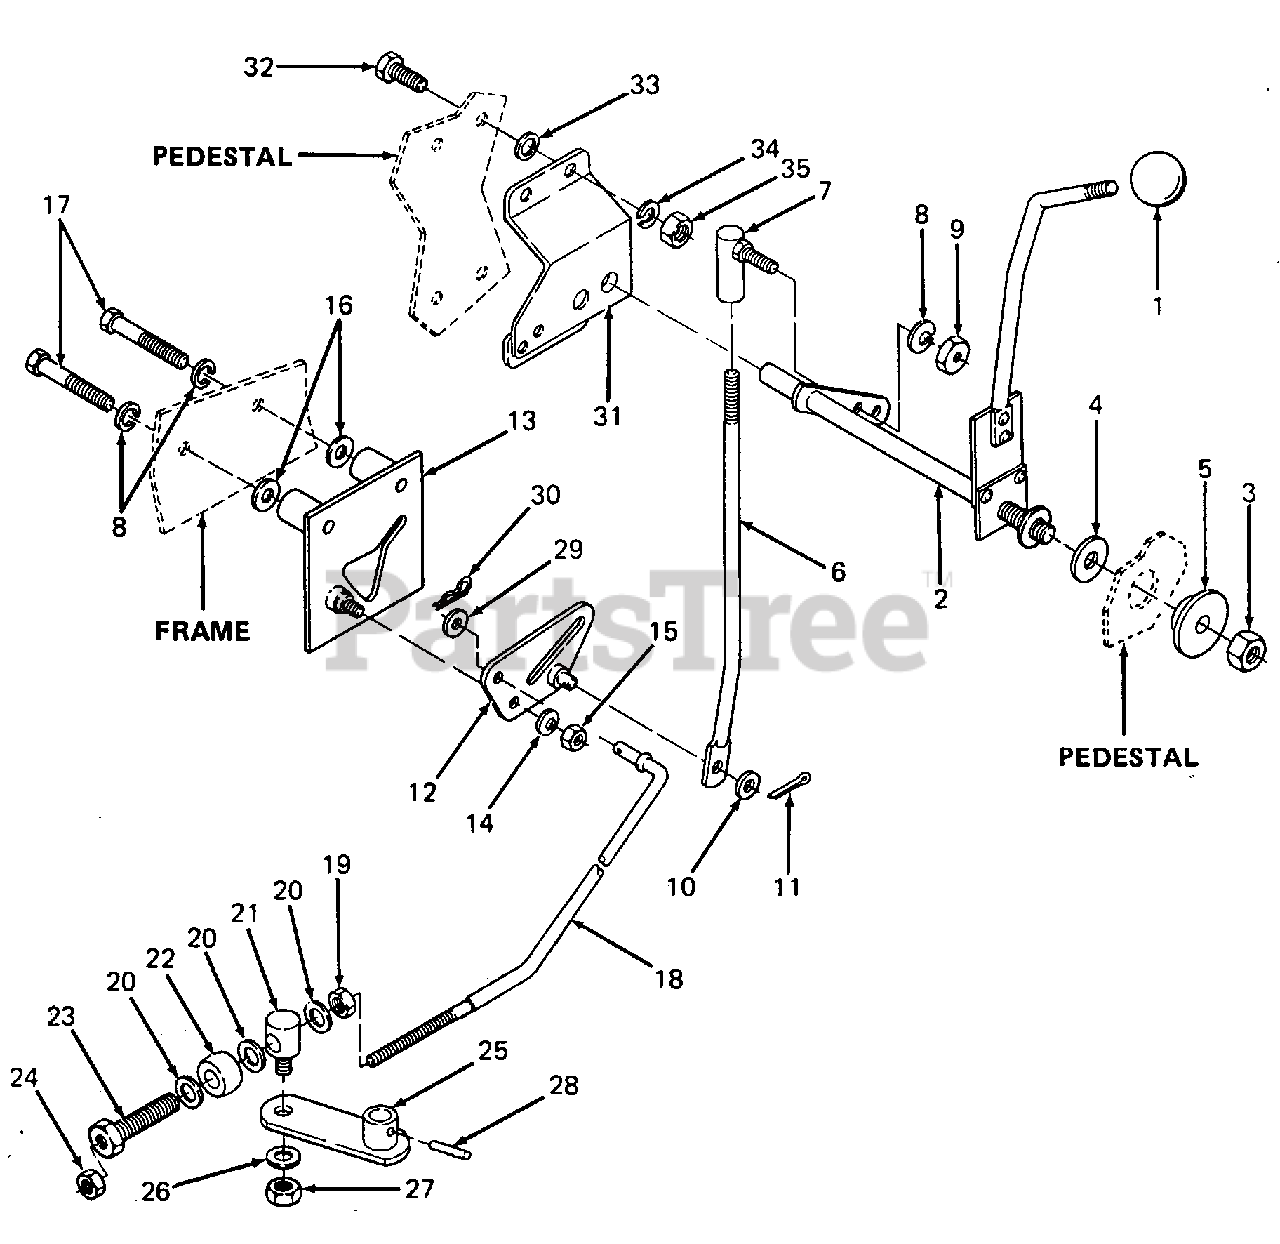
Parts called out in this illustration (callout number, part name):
1	Knob, Control
2	Shifter Assembly
3	Nut, Hex Top Lock, 1/2-20
4	Washer, Friction
5	Spacer, Shoulder
6	Rod, Upper Shift Control
7	Ball Joint
8	Washer, Lock, 3/8
9	Nut, Hex Patch Lock, 3/8-24 GR5
10	Washer, Flat, .406 X .75 X .063 Thk
11	Pin, Cotter, 3/32 Dia X .75 Lg
12	Lever, Cam
13	Plate, Cam
14	Washer, Bell
15	Nut, Hex Center Lock Jam, 3/8-24
16	Washer, Flat, .378 X 1.00 X .125 Thk
17	Screw, Hex Cap, 3/8-24 X 1.0 Lg
18	Rod, Hydro Control
19	Nut, Hex Patch Lock, 7/16-20
20	Washer, Flat
22	Washer, Rubber, .38 X .87
23	Stud, Adjustment
24	Nut, Hex, 5/16-24 GR5
26	Washer, Flat, .320 X .60 X .06 Thk HDN
27	Nut, Hex Patch Lock, 5/16-18
28	Pin, Slotted Roll, 5mm X 30mm Lg
29	Washer, Flat, .34 X .68 X .062 Thk
30	Pin, Internal Cotter
31	Bracket, Clutch Handle
32	Screw, Hex Cap, 1/4-20 X .62 Lg GR5
33	Washer, Flat, .281 X .75 X .105 Thk
34	Washer, Lock, 1/4
35	Nut, Hex, 1/4-20 GR5
